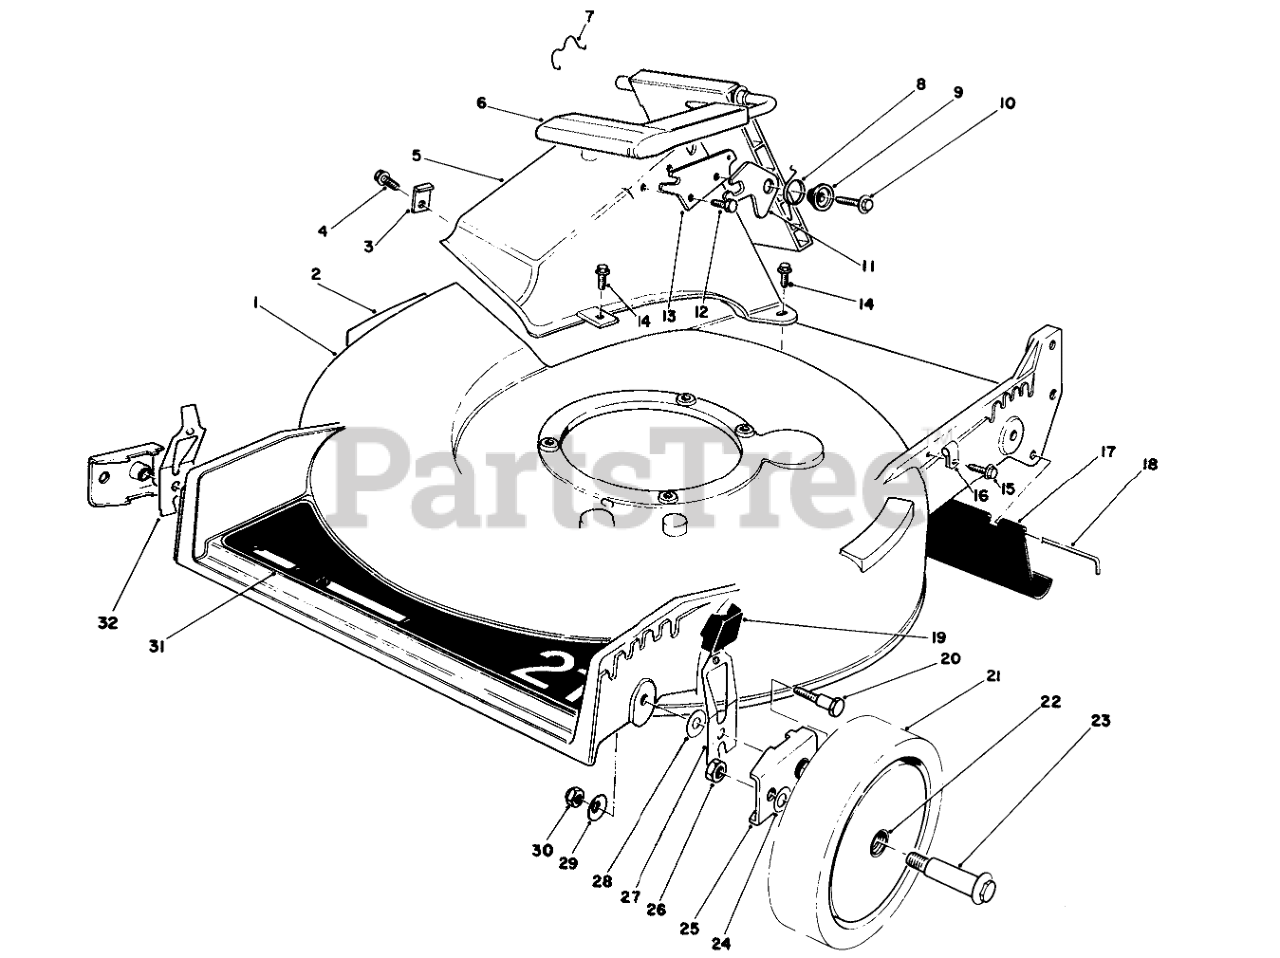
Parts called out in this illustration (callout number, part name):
1	Housing (Incl. Ref. #2)
2	DECAL-DANGER
3	TUNNEL CLIP
4	SCREW
5	Tunnel Discharge
6	Discharge Door Assembly
7	DOOR RET SPRING
8	TORSION SPRING
9	DOOR SPACER
10	SCREW-HWH
11	SAFETY LATCH
12	SCREW-PLASTITE
13	DOOR LATCH PLATE
14	SCREW-HWH
15	SCREW
16	CLAMP-CABLE
17	SHIELD-TRAILING
18	ROD-SHIELD
19	KNOB-ARM
20	PIVOT SCREW
21	Wheel & Tire Assembly (Incl. Ref. #22)
22	BUSHING
23	BOLT-WHEEL
24	WASHER
25	HP PIVOT ARM ASM
26	Nut
27	L. HP SPRING ARM ASM
28	WASHER-PIVOT
29	WASHER-BELLEVILLE
30	NUT-LOCK, NI
31	DECK DECAL
32	R HP SPRING ARM ASM
